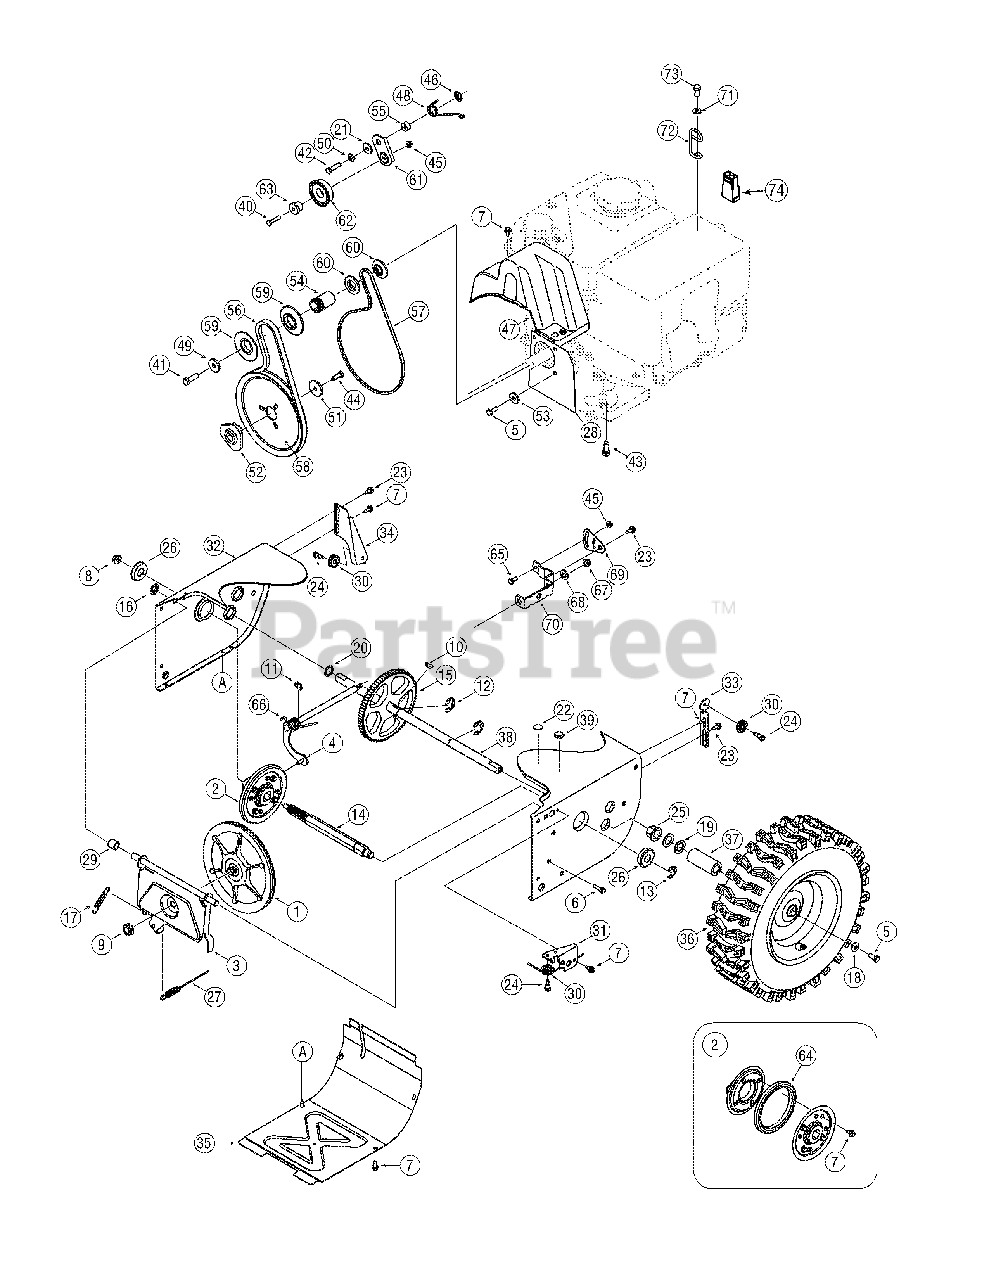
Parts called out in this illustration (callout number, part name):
1	Disc Assembly, Friction Wheel
2	Friction Wheel Assembly, 5.5 OD
3	Support Bracket, Friction Wheel
4	Shift Assembly, Rod
5	Hex Screw, 5/16-24, .750, Gr5
6	Screw, 1/4-20, 1.000
7	Screw, 1/4-20 x .625
8	Nut, Flange Lock, 3/8-16, Nylon
9	Nut, Jam Lock, 5/8-18, Gr5, Nylon
10	Key, Hi Pro, 3/16 x 3/4 Dia.
11	E-ring, .500 Dia.
12	E-ring, Retaining, .875 Dia.
13	E-ring, .750 Dia.
14	Hex Shaft, .8125, 7-Tooth
15	Gear, 80-Tooth
16	Speed Nut, .500
17	Extension Spring
18	Washer, Bell, .340 x .872 x .060
19	Washer, Flat, .793 x 1.24 x .060
20	Washer, Flat, .75 x 1.00 x .060
21	Spacer, Shldr., .3175 ID x .500 x .094
22	Plug, 1/2 ID
23	Screw, Shoulder, .37 x .105, 1/4-20
24	Screw, 1/4-28, .375
25	Bearing, Hex Flange x .75 ID
26	Bearing, Ball, 17 x 40 x 12
27	Clutch Cable, Wheel, 44.95"
28	Plate, Cover
29	Spacer, .508 ID x .75 OD x .68
30	Roller, Cable
31	Front Guide Bracket, Auger Cable
32	Frame
33	Guide Bracket, Auger Cable
34	Guide Bracket, Drive Cable
35	Cover, Frame
36	Wheel Assembly -RH
36	Wheel Assembly -LH
37	Spacer, 1.25 x .75 x 3.0
38	Axle, .75 x 22"
39	Plug, 3/8 ID
40	Hex Screw, 1/4-20, 1.25, Gr5
41	Hex Screw, 3/8-24, 1.25, Gr8
42	Hex Screw, 5/16-24, 1.25, Gr5
43	Screw, Sems, 3/8-16, 1.00
44	Hex Screw, 5/16-24, .875, Gr8
45	Nut, Flange Lock, 1/4-20, Nylon
46	Nut, Push-on, .25 Dia.
47	Cover, Belt
48	Spring, Torsion, .850 ID x .354
49	Washer, Flat, .406 x 1.25 x .157
50	Washer, Lock .3125
51	Washer, Flat, .34 x 1.50 x .150
52	Pulley, Adapter, .75 Dia.
53	Spacer, Shoulder
54	Spacer, .875 ID x 1.185 OD
55	Spacer, .340 x .750 x .360
56	Belt, Auger Drive
57	Belt, Wheel Drive
58	Pulley, Auger Drive, 8.1 x .5
59	Pulley, Half, V x 2.600 OD
60	Pulley, Half, 3/8-V x 1.7160 OD
61	Idler Bracket, Wheel Drive
62	Idler Pulley Assembly
63	Spacer, Shoulder, .26 x .79 x .538
64	Rubber, Friction Wheel, 5.5 OD
65	Hex Screw, 1/4-20, .620, Gr5
66	Spring, Torsion, .750 ID x .968
67	Nut, Flange Lock, 5/16-18, Nylon
68	Washer, Flat, .469 x .875 x .105
69	Pivot Bracket, Speed Selector
70	Shift Bracket, Speed Selector
71	Washer, Flat, .330 x .630 x .0635
72	Cable Control Wire
73	Screw, M8-1.25
74	Conn., Amp
